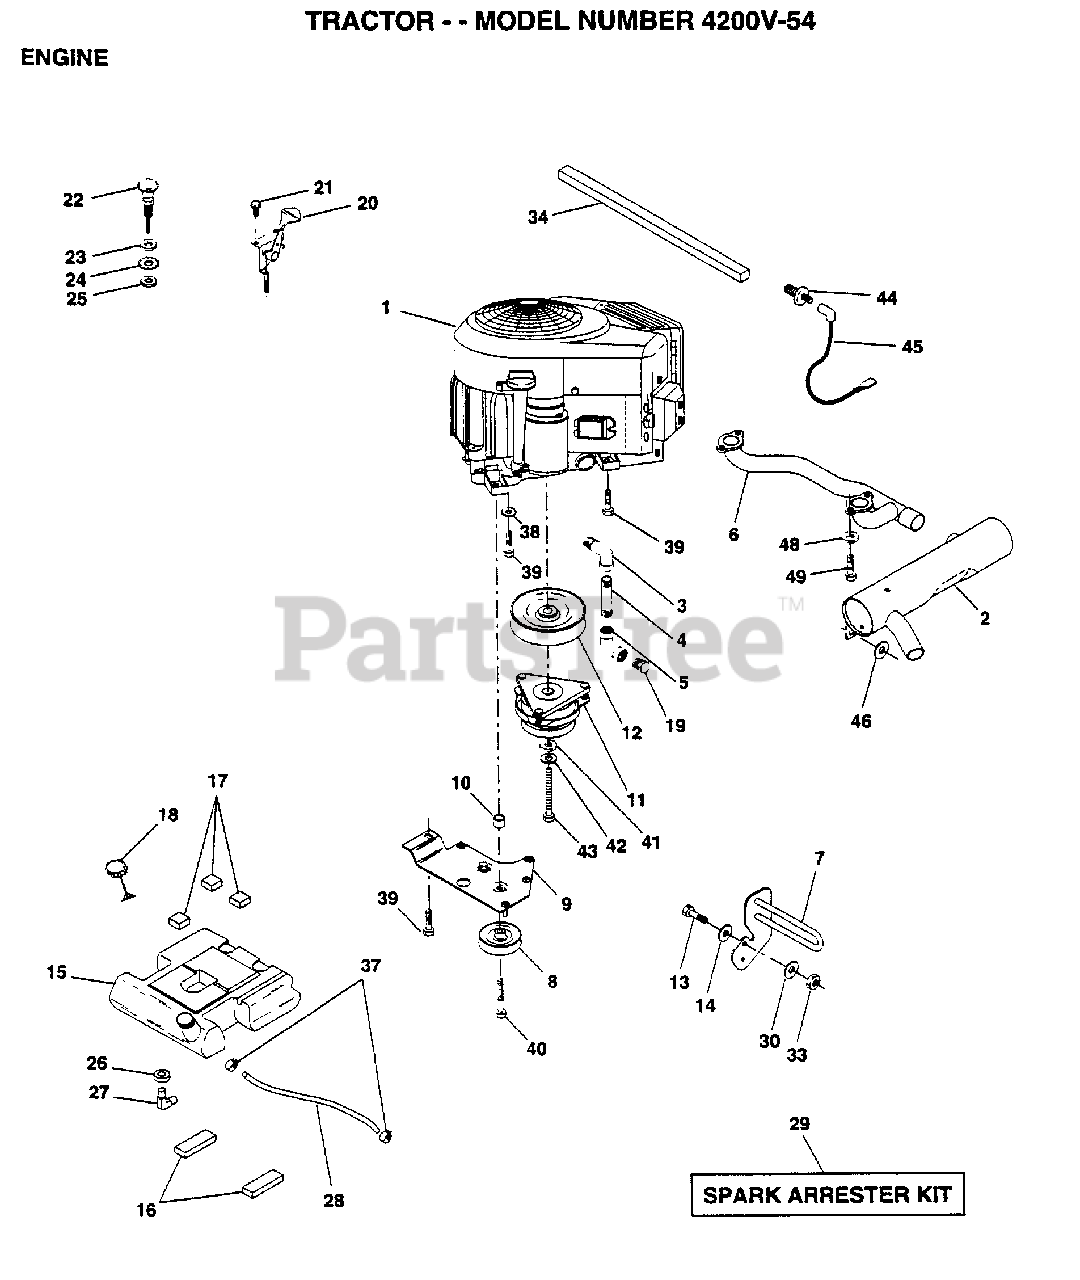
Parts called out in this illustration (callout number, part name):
3	STREET ELBOW LT
4	PIPE NIPPLE
5	ELBOW
6	PIPE.EXHAUST.B&S
10	BUSHING.
12	PULLEY.ENGINE.VGT
13	"BOLT,HEX"
14	WASHER
16	PAD IDLER TI
17	PAD-SPACER LT
18	CAP ASM FUEL
19	PLUG T
21	SCREW LT
23	WASHER
24	LOCKWASHER
26	BUSHING OUTLET T
27	STEM.TANK.FUEL
29	SPARK ARREST KIT
30	WASHER T
33	NUT
34	FOAM-STRIP LT
37	HOSE CLAMP
38	LOCKWASHER
39	SCREW LT
40	SCREW.3/8-16X3.25
41	WASHER
42	LOCKWASHER
44	SWITCH OIL KOHLER
45	WIRE.LEAD.SENTRY
46	WASHER HYT
48	LOCKWASHER
49	BOLT.HD.SOCKET.
